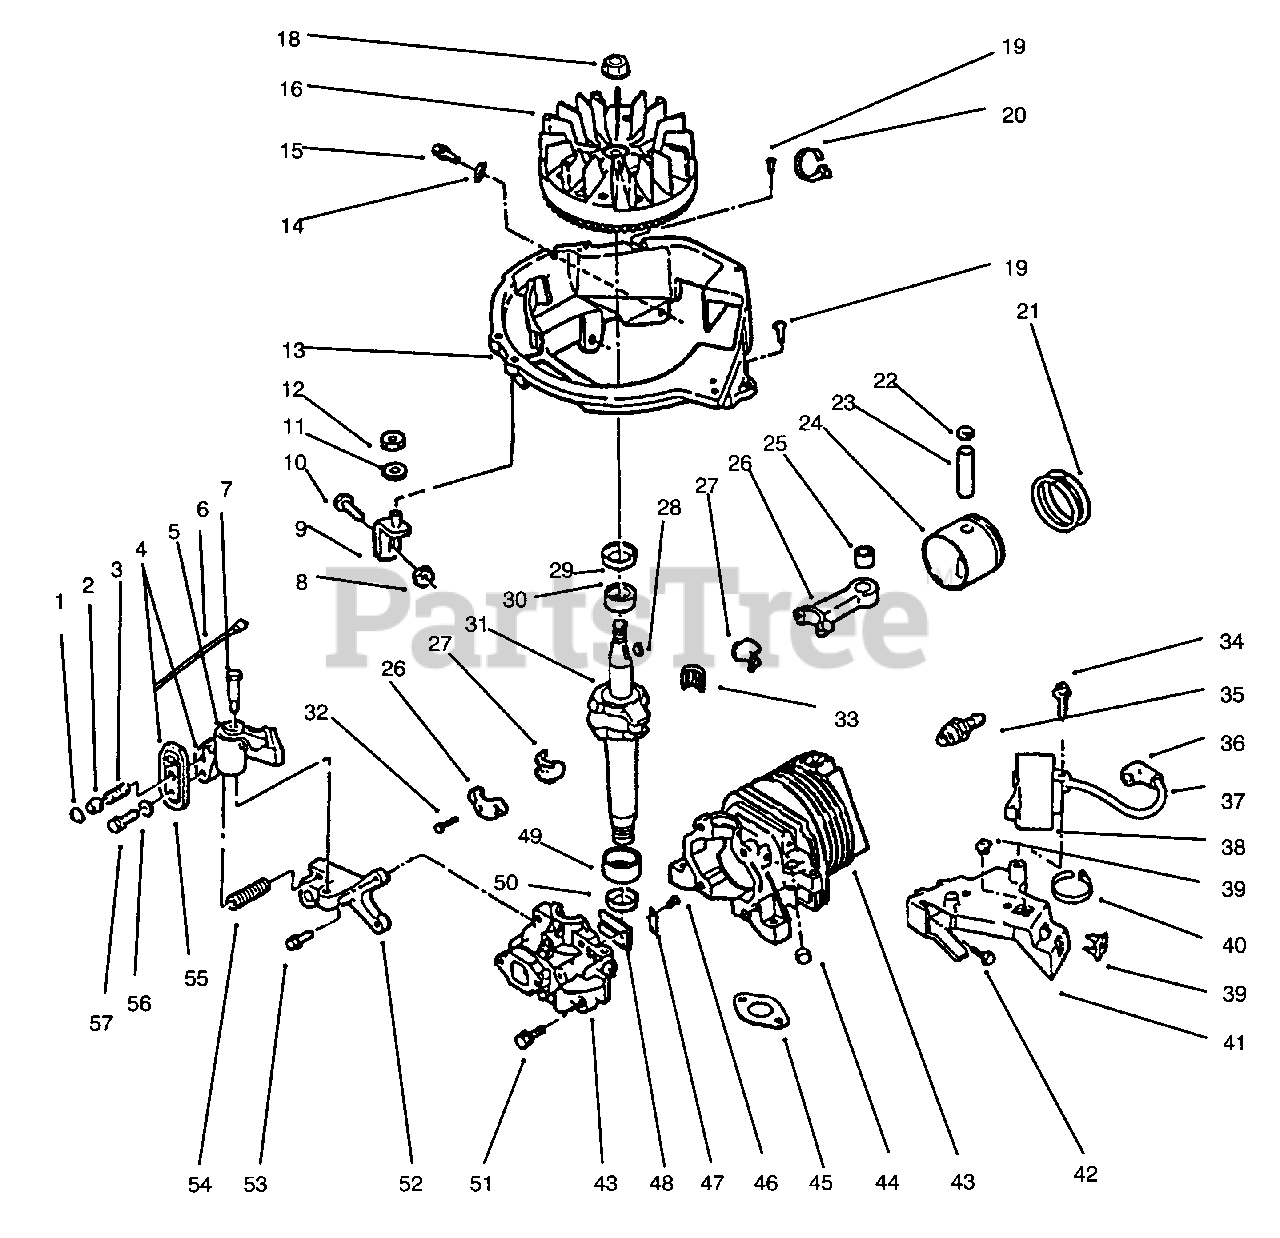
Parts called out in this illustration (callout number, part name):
1	Retainer
2	Actuator-Brake Lever
3	Spring-Cable, Return
4	Assembly-Switch (incl. Ref. #1, 6, 20, & 56-58)
5	Assembly-Brake
6	Wire Lead
7	Bolt-Shoulder
9	Assembly-Brace
11	Washer
13	Shroud-Base
14	Clip-"J"
16	Assembly-Flywheel
18	Nut-Flywheel
20	Tie Strap
21	Set-Ring
22	Ring-Retaining
23	Pin-Wrist
24	Assy.-Piston & Conn. Rod (Incl. Ref. #24-27,& 32-33)
25	Assembly-Bearing
26	Assembly-Conn. Rod (Incl. Ref. #25-27 & 32-33)
27	Liner-Split
28	Key-Flywheel
29	Seal-Oil
30	Bearing-Main
31	Crankshaft
33	Set-Needle Bearing
34	Screw
35	Spark Plug
36	Cover-Terminal
37	Wire Lead
38	C.D. Ignition Module (Incl. Ref. #36-37)
39	Nut-Speed
40	Tie Strap
41	Bracket-C.D.
43	Assy.-Cyl./Crankcase Cov. (Incl. Ref. # 46-48,51 & 53)
45	Gasket-Exhaust
47	Plate-Reed
49	Bearing-Main
50	Seal-Oil
52	Bracket-Brake
54	Spring-Brake
55	Assembly-Case
56	Washer
57	Screw
